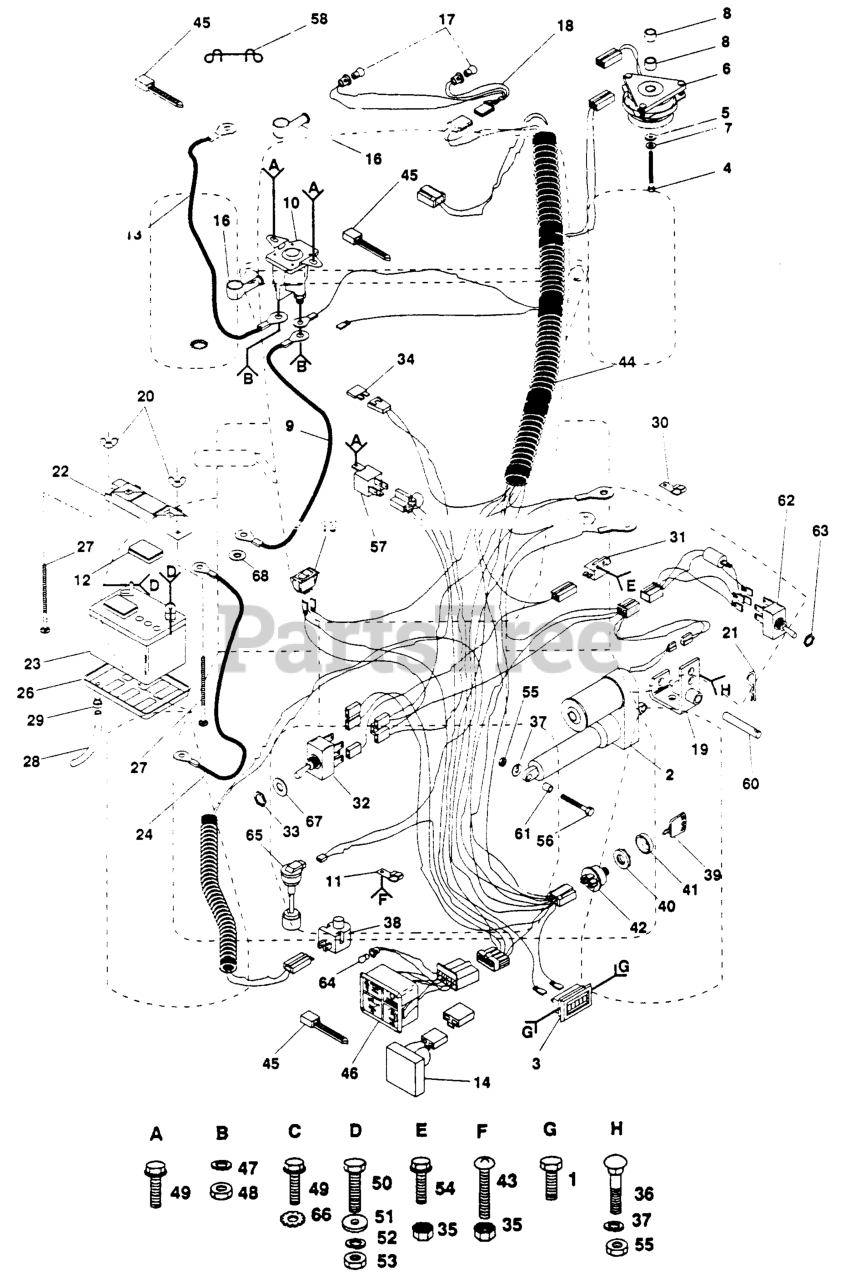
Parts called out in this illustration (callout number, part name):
1	Screw # 10-24 x 1/2
2	ELECT ACTUATOR
3	HOUR METER T
4	Bolt, Hex 7/16-20 x 1-1/2 Gr. 8
6	ELECTRIC CLUTCH T
7	LOCKWASHER
8	SPACER-CLUTCH GT
9	CABLE-BATTERY YTV
10	SOLENOID KIT
11	CLIP T
12	CAP BATTERY NLA
13	CABLE, STARTER
14	SENSOR LOW VOLTAGE
16	TERMINAL COVER
17	BULB-LIGHT T
18	HARNESS, LIGHT SOCKET
20	WING NUT
22	TERMINAL GRD YTV
23	BATTERY
24	CABLE T
26	BATTERY TRAY T
28	BATT DRAIN TUBE T
29	HOSE CLAMP T
31	SWITCH-INTER. GT
32	SWITCH,PTO
33	HEX NUT T
35	Nut, Keps #10-32
36	BOLT D
37	WASHER, LOCK 3/8
38	RP.SWITCH.PLUNGER.NC.GRAY
39	KEY.MOLDED.GENERIC
40	NUT IGNITION
41	COVER KEY IGNITIO
42	SWITCH
44	HARNESS, IGNITION
45	TIE GUIDE
46	LIGHT PACKAGE
47	LOCKWASHER
48	NUT
49	SCREW ST
50	BOLT.HEX.1/4.X.3/4.DICHROMATE
51	WASHER
52	LOCKWASHER
53	NUT
54	SCREW **
55	NUT.HEX.3/8-16UNC
56	BOLT-HEX EAK
57	RELAY.ASSY.T
60	PIN-ACTUATOR T
62	LIFT,SW WIRING
63	LOCKWASHER
64	BULB LIGHT T
65	SENSOR, LOW FUEL
66	LOCKWASHER
67	WASHER
68	Washer, Lock, Int. tooth 1/4
